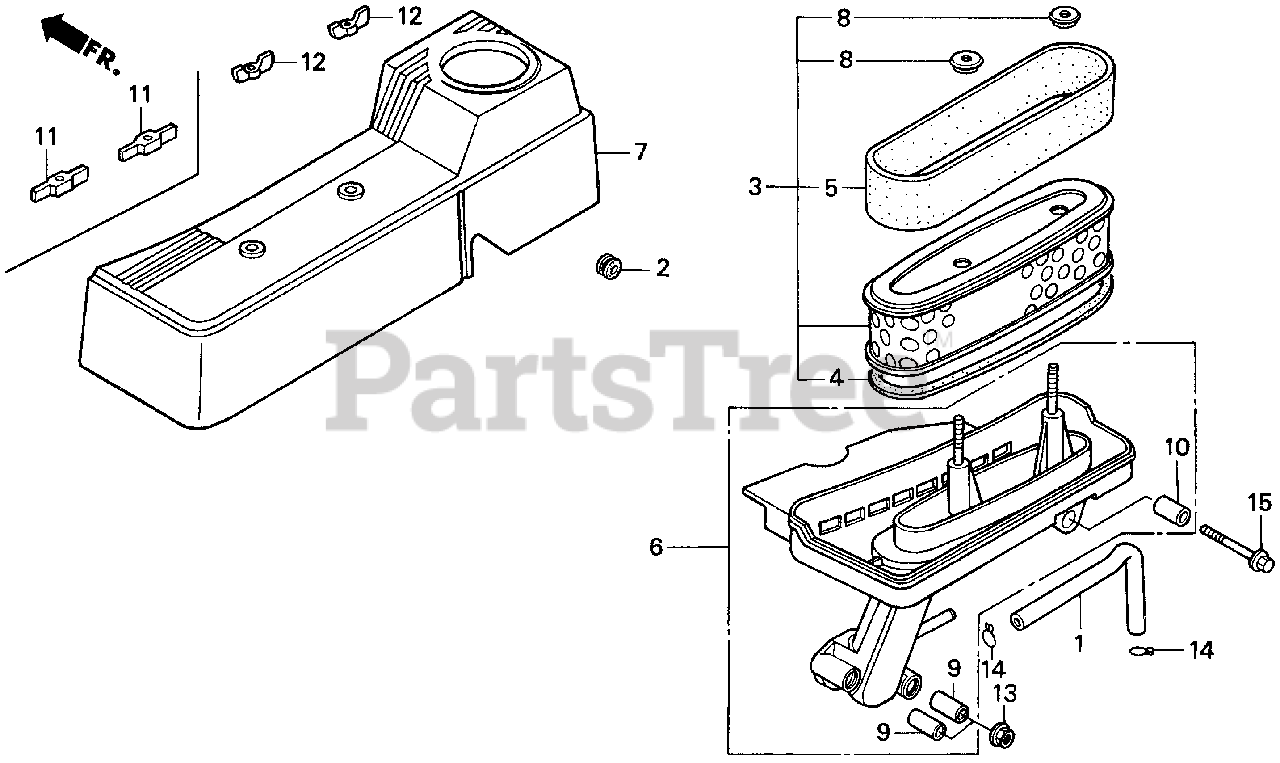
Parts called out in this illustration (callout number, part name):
1	TUBE, BREATHER
2	GROMMET, CHOKE ROD
3	ELEMENT, AIR CLEANER
4	GASKET, ELEMENT
5	FILTER (OUTER)
6	HOUSING, AIR CLEANER
7	COVER, AIR CLEANER
8	GROMMET, AIR CLEANER
9	COLLAR, AIR CLEANER
10	COLLAR B, AIR CLEANER
11	WINGNUT (6MM)
12	WINGNUT, TOOL BOX SETTING
13	NUT, FLANGE (6MM)
14	CLIP, TUBE (B12)
15	BOLT, FLANGE (6X35)
